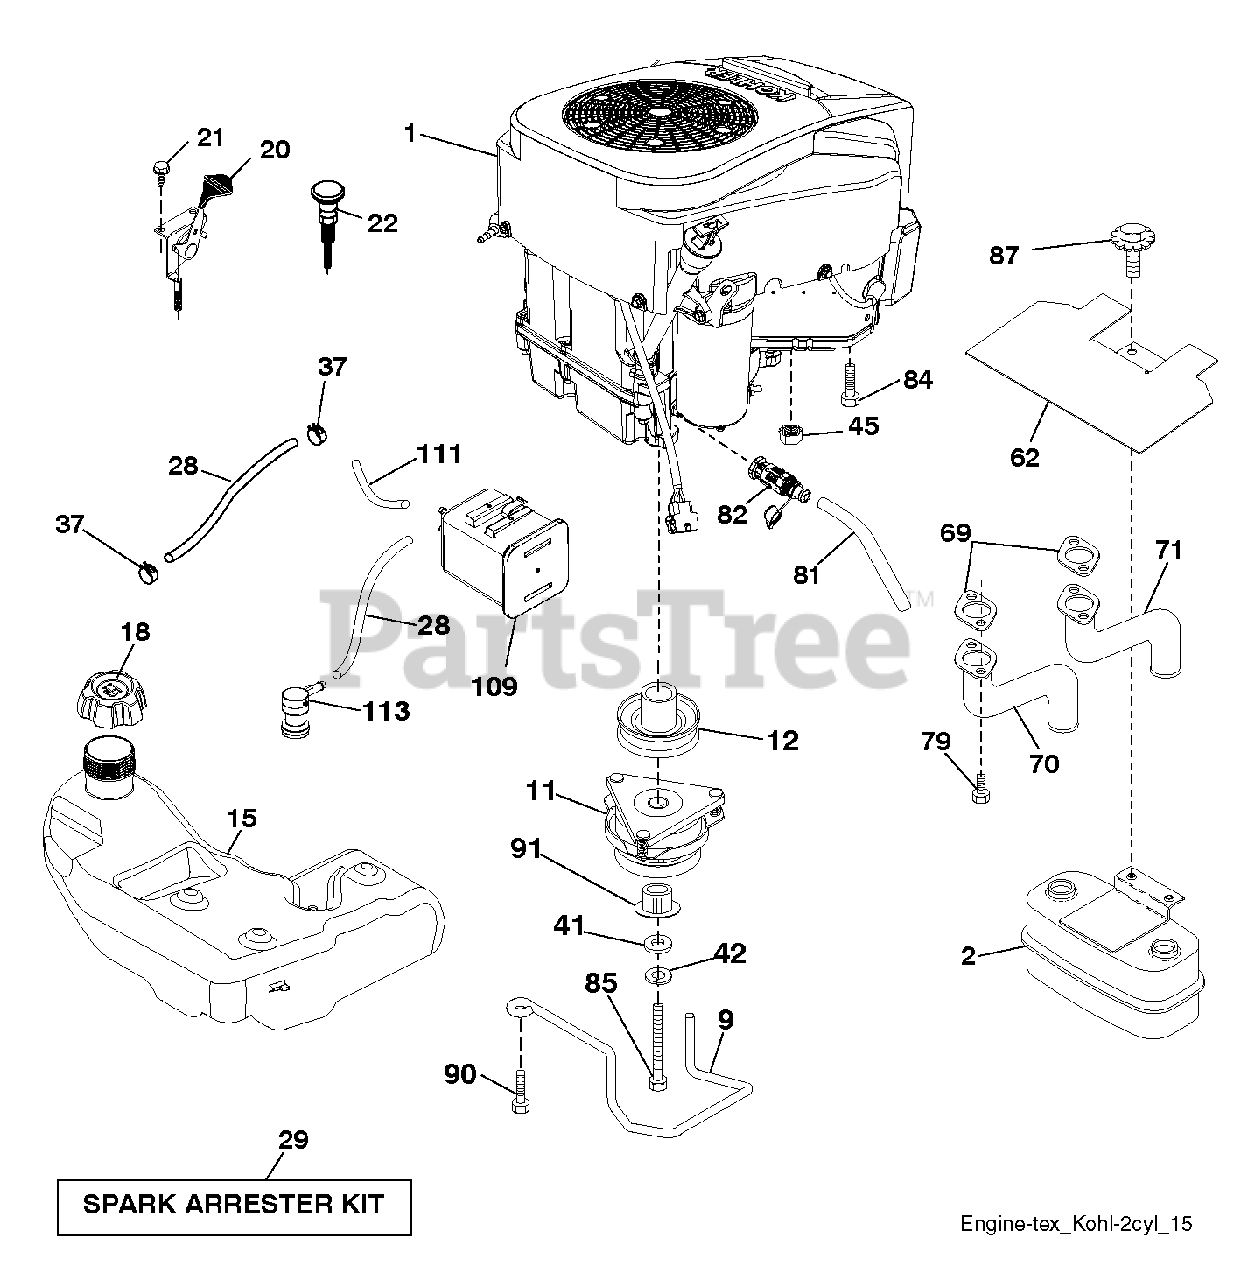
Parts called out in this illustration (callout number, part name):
2	MUFFLER.ASM.TWN.EXTNDED.DFLCTR
9	KEEPER.BELT.ENGINE.4.2
11	CLUTCH.ELECTRIC.LT.48"*
12	PULLEY.ENGINE.TUFFTORQ
15	TANK.ASM.FUEL.3GA.CARB
18	CAP.ASM.FL.RITCH.3"E10.SYM.498
20	THROTTLE CONTROL
21	SCREW.#10 X 0.750.BOS
22	CONTROL.CHOKE.ERGO.PUSH-IN.BLA
28	LINE.FUEL.64"REAR.EMIS
29	KIT.SPARK ARRESTOR 794945 B&S
37	HOSE CLAMP
42	LOCKWASHER
45	NUT
62	SHIELD.HEAT.MUFFLER
69	GASKET.EXHAUST.KOHL.CV18-CV26
70	RP.PIPE-EXHAUST LH
71	RP.PIPE-EXHAUST RH
79	SCREW.SOCKET HD.5/16-1
81	TUBE, DRAIN OIL ASM.
82	VALUE.OIL.DRAIN
84	SCREW 3/8-16X1
85	BOLT HEX 7/16-20X4-1/4"
87	BOLT, 5/16-18 X 1 3/4
90	SCREW 3/8-16X1
91	PARTNER DECAL,
109	CANNISTER, CARBON
111	PURGE.LINE.36"REAR.CALIFORNIA
113	VALVE.SLANT.CARTRDG.90 DEG.TEX
